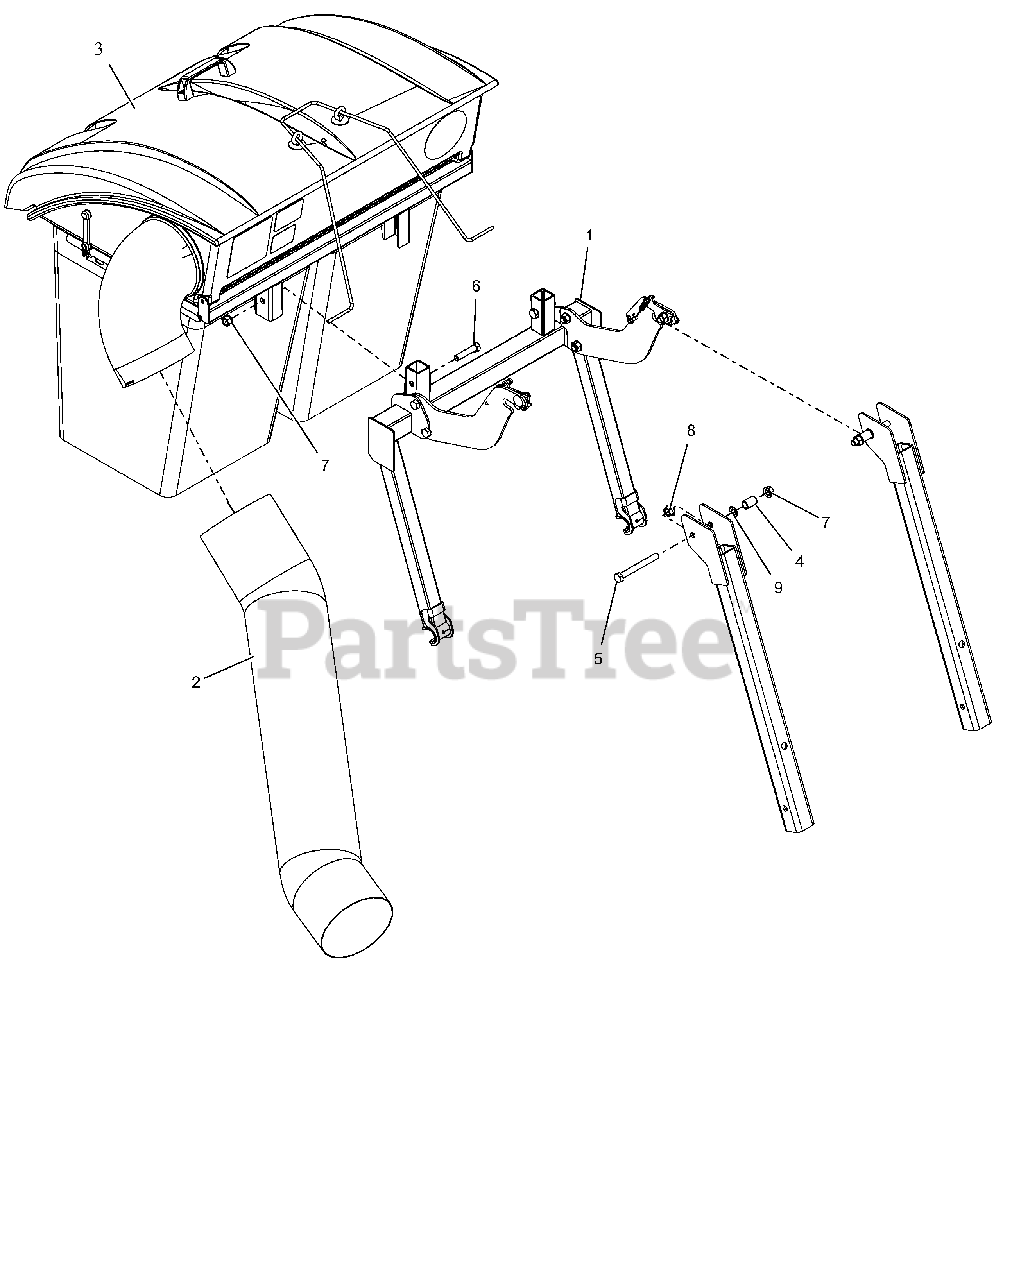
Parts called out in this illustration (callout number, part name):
1	WLDMT, BAGGER POST HD BLACK
2	HOSE, FLEXIBLE-47"
3	BAGGER, PECO 2-BAG RECEPTACLE
3	CLAMP, 7' BAGGER HOSE
3	HOOD ASM PECO 2 BAG
3	FRAME ASM PECO 2 BAG
3	RUBBER HOOD STRAP
3	HANDLE
3	ROPE, BAGGER RELEASE
3	ELBOW, PECO BAGGER
4	SPACER .510 X .75 X 1.1485
5	@BLT-HEX .5-13-4.5GR8 FULL THD
6	@BLT-HEX .50-13X2.25 GR5 YWZC
7	@NUT-LK-TOP-FLG .50-13 YWZC
8	NUT-SPNLK-FLG .50-13 YWZC
9	WSHR-FL-STL .505X.880X.072 YWZ
